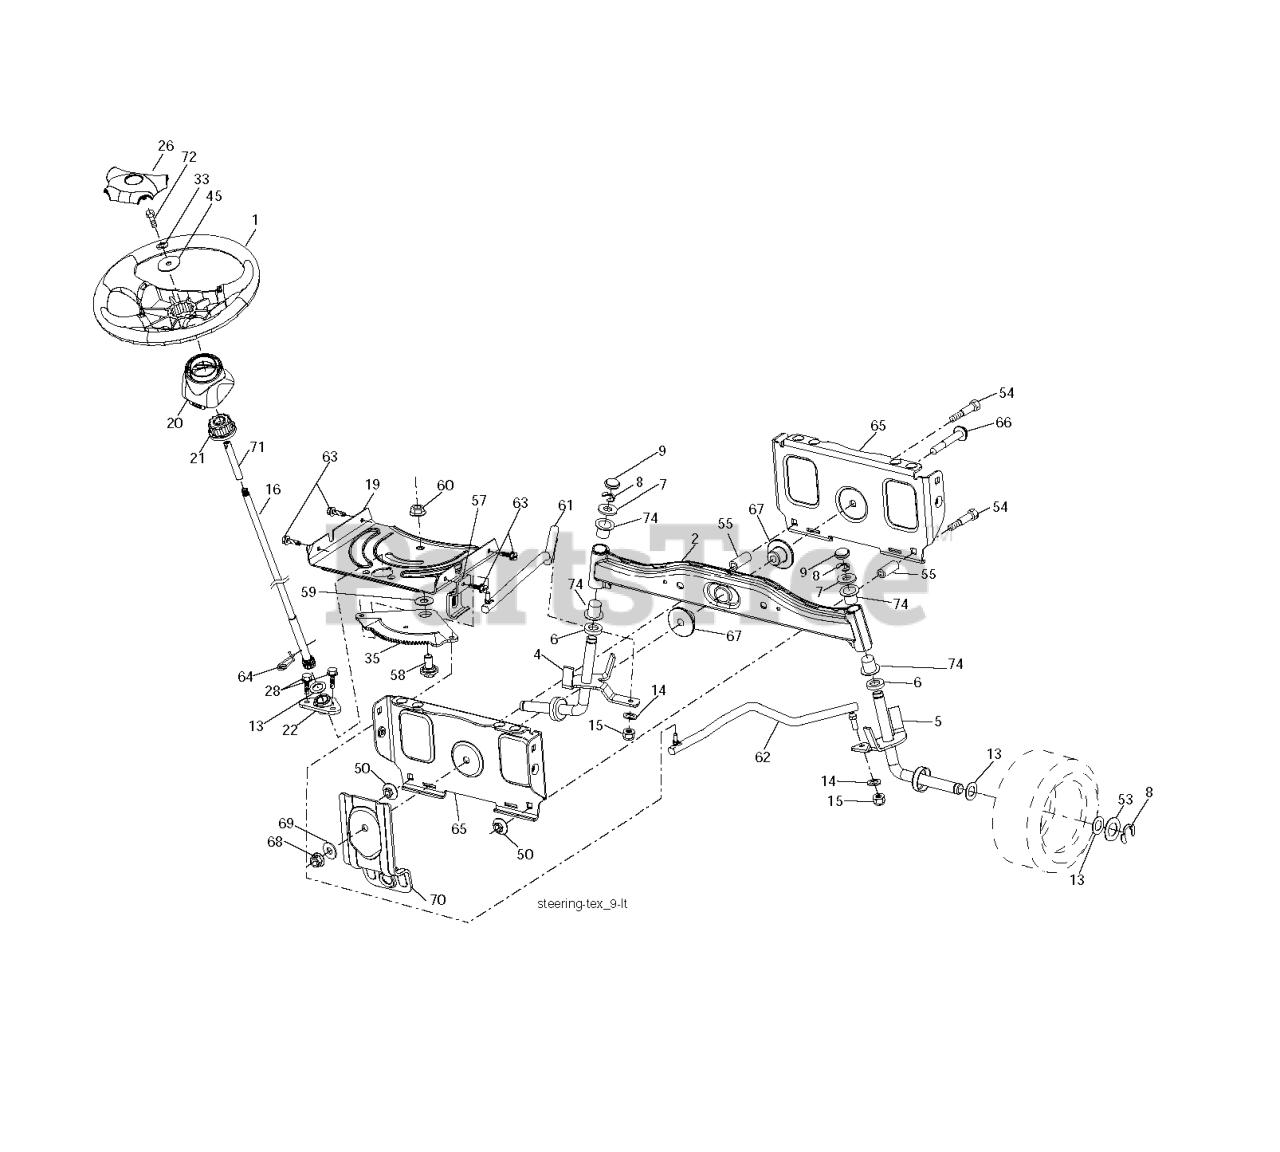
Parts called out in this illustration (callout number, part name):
1	WHEEL.STEERING.LEGEND2.GRY
2	AXLE.HALF.ASM.WELDED
4	SPINDLE.WELDED.LH.15"TEX
5	SPINDLE.WELDED.RH.15"T
6	THRUST WASHER
9	CAP.SPINDLE.BLACK
14	WASHER, LOCK 3/8
15	NUT CROWNLOCK 3/8-24
16	SHAFT STEERING
19	PLATE.STEER.DDL.NLT/NG
20	BOOT, STEERING
21	ADAPTER, WHEEL STNG..
22	BUSHING.ASM.STEERING.A
26	INSERT.CAP.STRG.WH.GRAY
28	SCREW, 3/8-16X3/4
33	WASHER.LOCK.HVY.HLCL.SPR.5/16
35	GEAR.SECTOR.PLATE.DDL.
45	WASHER.11/32
50	NUT LOCK FLG 3/8-16 UNC
53	WASHER.HARDENED
55	SPACER.BRACE.AXLE (2 2)
57	BRACKET.UPSTOP.TEX
58	BOLT.SHOULDER.SECTOR.P
59	WASHER.THURST.SECTOR.S
60	NUT FLANGE LOCK 5/8-11
61	DRAGLINK.LH.BALLSTUD.D
62	DRAGLINK.RH.BALLSTUD.D
63	SCREW
64	RETAINER.CLIP.SPRING.S
65	BRACE.AXLE.FRONT.NLT/N
66	BOLT HEX FGHD 7/16-14 X 3 SERR
67	BUSHING.PM.FRONT AXLE
68	NUT.LOCK.FLANGE.7/16
69	WASHER.1.5X.505X.118
70	BRKT.DECK.SUSPENSION.F
71	SHAFT EXTENSION STEERING
72	BOLT YT
74	BRNG T
